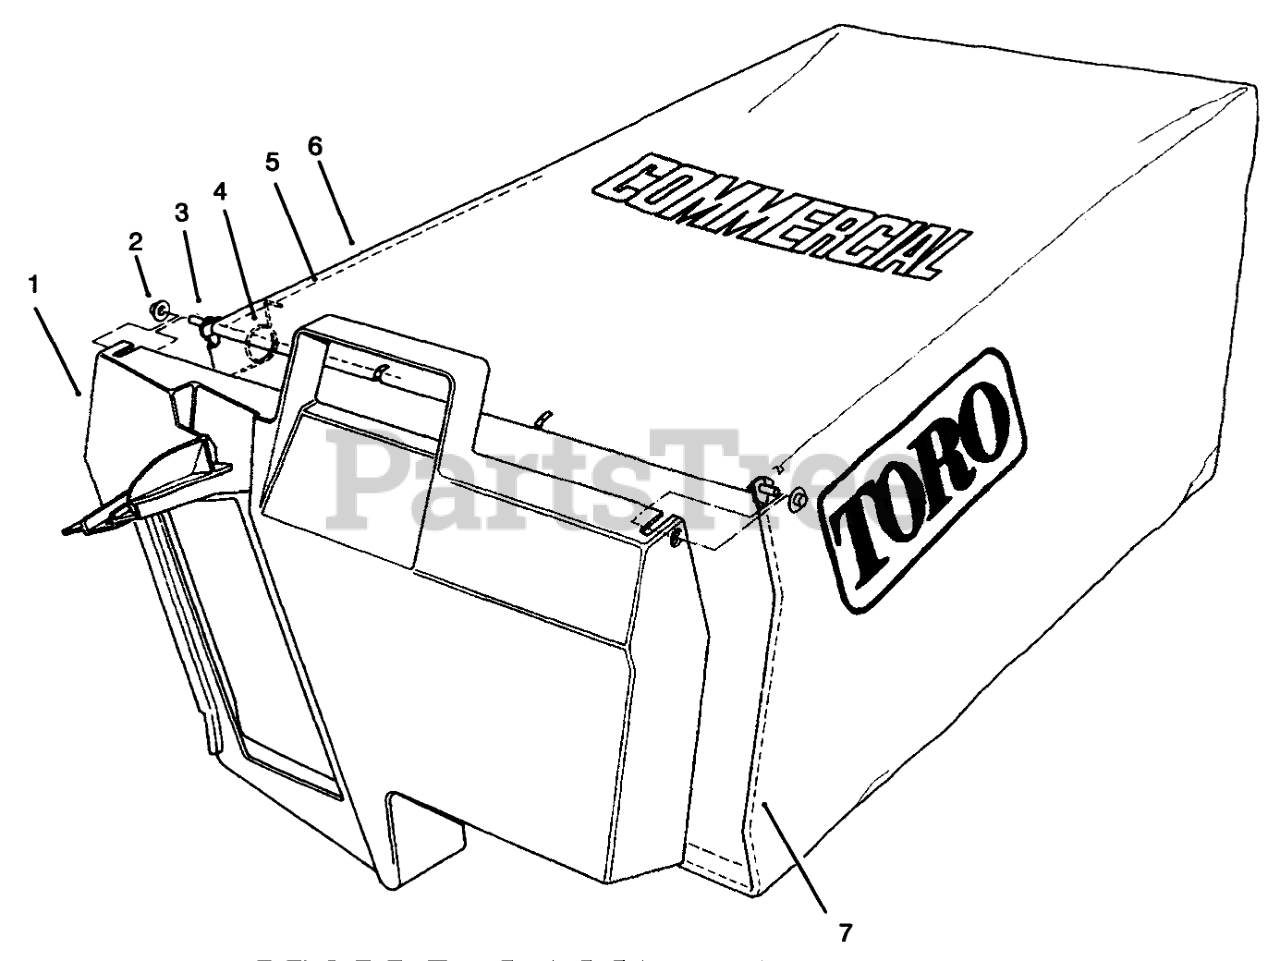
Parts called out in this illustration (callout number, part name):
1	DOOR-BAG, GRASS
2	NUT-PUSH
3	HINGE-DOOR, BAG
4	SPRING
5	FRAME-BAG, UPPER
6	Bag
7	FRAME-BAG
